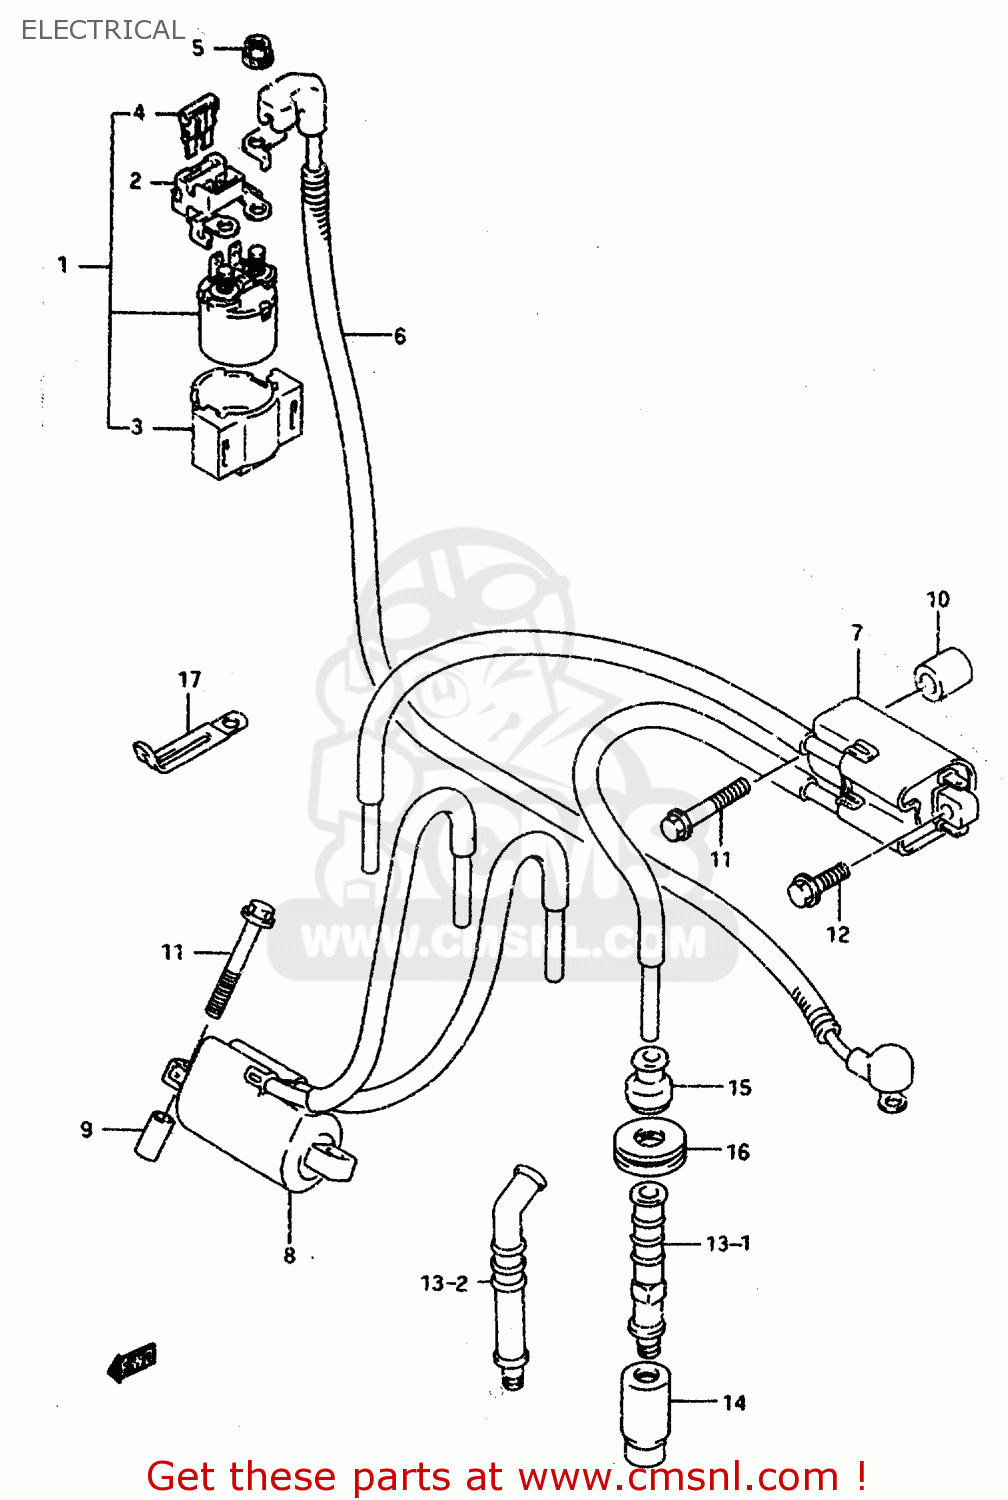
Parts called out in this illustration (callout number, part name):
1	RELAY ASSY,STARTING MOTOR
2	TERMINAL,RELAY
3	BRACKET,STARTING MOTOR RELAY
4	FUSE (30A)
5	NUT
6	WIRE,STARTER MOTOR
7	COIL ASSY,IGNITION
8	COIL ASSY,IGNITION
9	SPACER(6.5X9X18)
10	SPACER,IGNITION COIL 1
11	BOLT
12	BOLT
13	CAP,SPARK PLUG
14	SEAL,SPARK PLUG
15	SEAL,HIGH TENSION CORD
16	COVER,SPARK PLUG CAP
17	CLAMP
